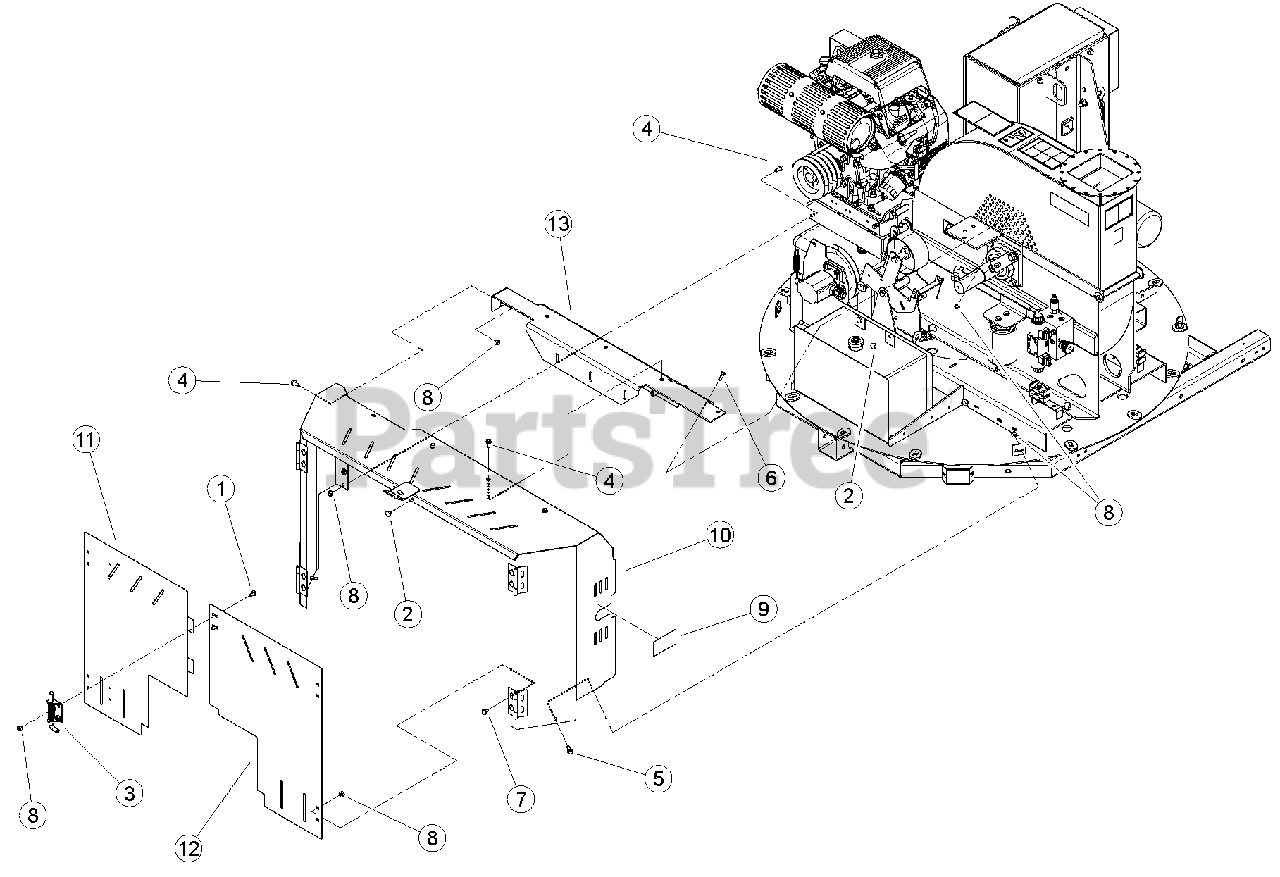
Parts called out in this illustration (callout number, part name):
1	BOLT, 5/16-18 X 3/4 GR5 CRG SN
2	BUMPER, RUBBER
3	LATCH, RH HINGE
4	BOLT, 5/16 X 3/4 FLANGE NC
5	BOLT, 5/16 X 1 FLANGE NC
6	BOLT, 5/16 X 1" GR5 CRG ZP
7	BOLT, 5/16 X 5/8 GR5 CRG ZP
8	NUT, 5/16-18 NYLOCK-FLANGE
9	DECAL, FEED SPEED
10	WELDMENT, BELT SHIELD FRAME
11	WELDMENT, 8" LEFT DOOR
12	DOOR, 8" RIGHT
13	WELDMENT, ENGINE TIE
